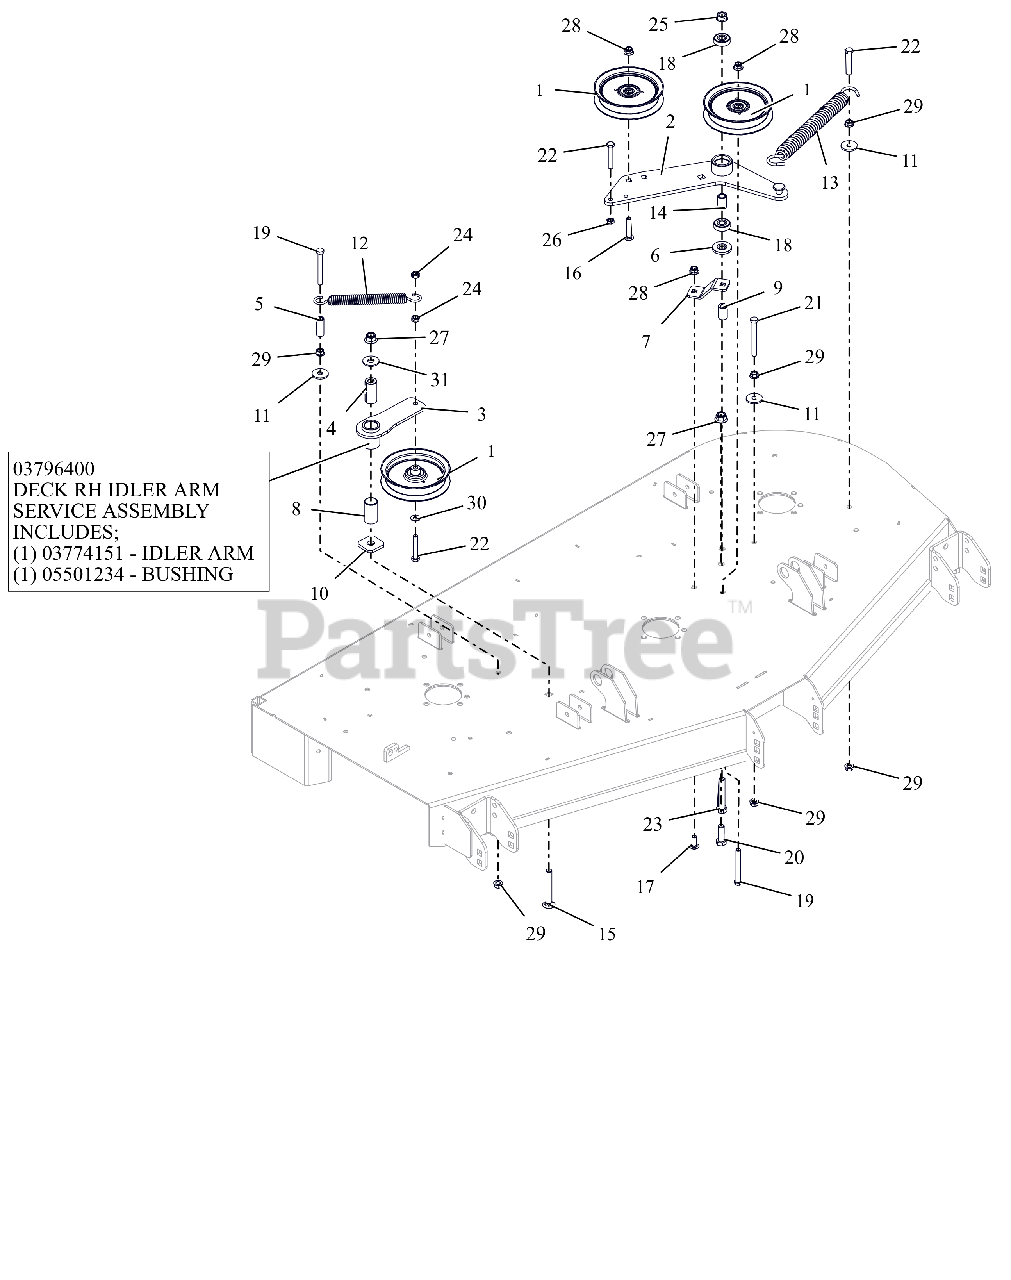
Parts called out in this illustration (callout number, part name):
1	IDLER, FLAT 5.00"
2	DECK PTO IDLER ARM WLDMT - BLK
3	WMT, IDLER ARM - BLACK
3	ASM, IDLER ARM (DECK)
3	BSHG, 1.00X1.125X1.937
4	BSHG, SPCR .502X.997X2.03 PM
5	SPACER, .375IDX.625ODX1.66 PM
6	SPACER, IDLER ARM
7	PTO FIXED IDLER MTG BRKT-ORG
8	BSHG, 1.00X1.125X1.937
9	BUSHING, SLV .380X.750X1.190
10	WSHR-FLT .640X1.75X.250
11	WSHR-FL-STL .406X1.375X.135 YZ
12	SPRING, EXTENSION
13	SPRING, EXTENSION
14	SPACER .510 X .75 X 1.1485
15	@BLT-RDHDSQNK .50-13X3.50 G5YZ
16	BLT-RDHDSQNK .38-16X2.00 SHTYW
17	@BLT-RDHDSHSQNK.38-16X1.0 G5YZ
18	BRG-BALL .500X1.38X.437
19	@BLT-HEX .38-16X3.25 GR5 YWZC
20	@BLT-HEX .50-13X1.50 GR5 YWZC
21	@BLT-HEX .38-16X3.50 GR5 YWZC
22	@BLT-HEX .38-16X2.25 GR5 YWZC
23	@BLT-HEX .50-13X3.00 GR5 YWZC
24	@NUT-LK-CTR .38-16 YWZC
25	NUT-LK-CTR-FLG .50-13 YWZC
26	NUT-HEX-JAM .375-16 YWZC
27	@NUT-LK-NYL-FLG .50-13 YWZC
28	@NUT-LK-NYL-FLG .38-16 YWZC
29	@NUT-SPNLK-FLG .375-16 YWZC
30	@WSHR-FL-STL.406X.812X.065 YWZ
31	@WSHR-FL-STL.563X1.38X.109YWZC
